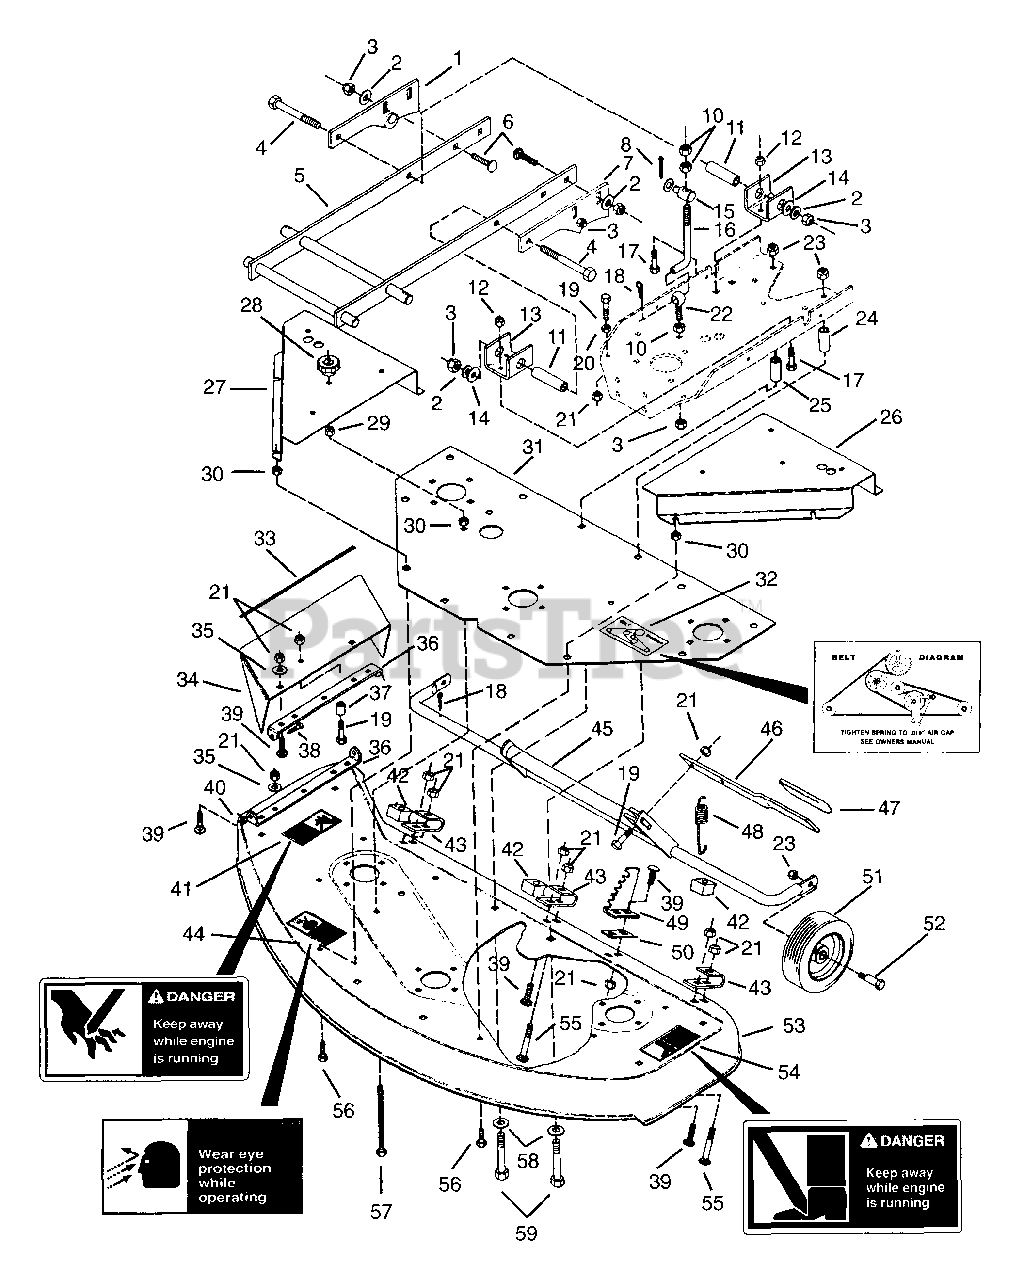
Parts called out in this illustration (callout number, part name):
1	Weldment, Deck Leveling Right Hand
2	Washer-Flat-Steel .531 x 1.250 x .100
3	Nut-Locking .50-13
4	Bolt-Hex .50-13 x 3.25 Grade 5
5	Weldment, Pivot Arm
6	Bolt-Round Head Square Neck .50-13 x 1.25
7	Weldment, Deck Leveling Left Hand
8	Pin-Cotter .12 x 1.25
9	Washer-Flat-Steel .531 x 1.000 x .063
10	Nut-Jam .50-13 Grade 2
11	Spacer .510 x .750 x 2.02 Steel
12	Nut-Locking .312-18
13	Support, Mower Pivot
14	Washer-Flat-Steel .813 x 1.370 x .100
15	Pivot, Mower Lift
16	Rod, Lift
17	Bolt-Hex .31-18 x .88 Grade 5
18	Pin-Cotter .12 x 2.0
19	Bolt-Hex .38-16 x 1.50 Grade 5
20	Nut-Jam .375-16
21	Nut-Locking-Nylon .375-16 Grade 2
22	Bolt, Eye
23	Nut-Locking-Nylon .50-13 Grade 5
24	Spacer .510 x .840 x 2.437 Steel
25	Spacer .560 x .750 x 2.437 Steel
26	Cover, Belt Left Hand
27	Cover, Belt Right Hand
28	Knob
29	Nut-Locking-Nylon .312-18 Grade 2
30	Nut-Jam .312-18
31	Plate, Support
32	Decal, Belt Installation
33	Stripe
34	Chute, 40" Flip-Up
35	Washer-Flat-Steel .406 x .812 x .065
36	Bracket, Chute 40" Mower
37	Bushing-Sleeve .407 x .625 x .750
38	Bolt-Hex .25-20 x .875
39	Bolt-Round Head Square Neck .38-16 x 1.0
40	Nut-Locking-Nylon .250-20 Grade 2
41	Decal, Danger Hand
42	Stop, Nylon
43	Bracket, Axle Support
44	Decal, Warning Eye
45	Weldment, Axle Pivot
46	Lever, Height of Cut
47	Grip, Handle
48	Spring-Tension .095 x .85 x 4.38
49	Bracket, Height Adjustment
50	Shim, Mower Height Adjuster Bracket
51	Tire/Wheel Assembly 6 x 2
52	Bolt, Eccentric
53	Weldment, 40" Mower Deck
54	Decal, Danger Foot
55	Bolt-Round Head Square Neck .38-16 x 2.00
56	Bolt-Hex .31-18 x .75 Grade 5
57	Bolt-Round Head Square Neck .31-18 x 3.5
58	Washer-Flat-Steel .531 x 1.062 x .095
59	Bolt-Hex .50-13 x 3.75
